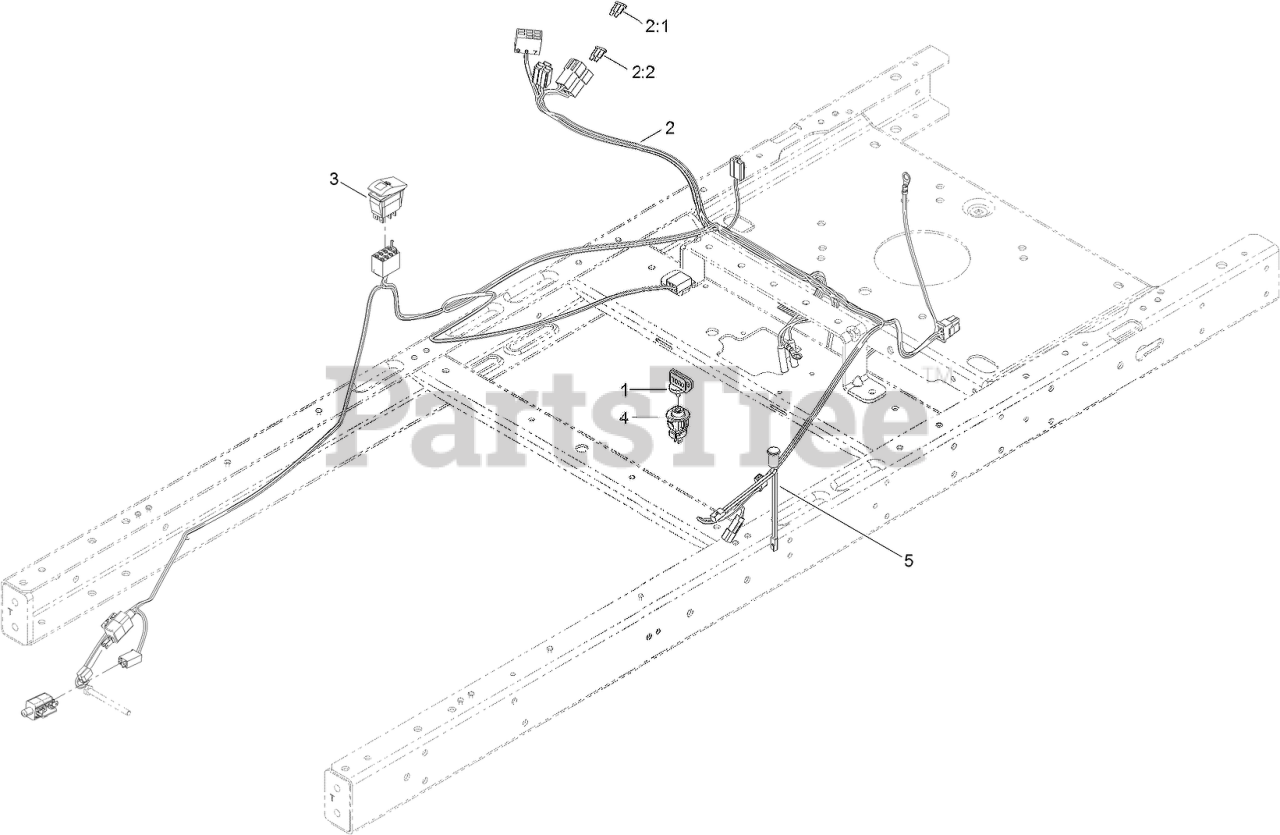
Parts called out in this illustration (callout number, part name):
1	KEY-TORO
2	HARNESS-WIRE
2:1	FUSE-BLADE, 30 AMP
2:2	FUSE-BLADE, 25 AMP
3	SWITCH-ROCKER, (ON)-OFF-(ON)
4	SWITCH-MOMENTARY, N.O.
5	LIGHT-INDICATOR
